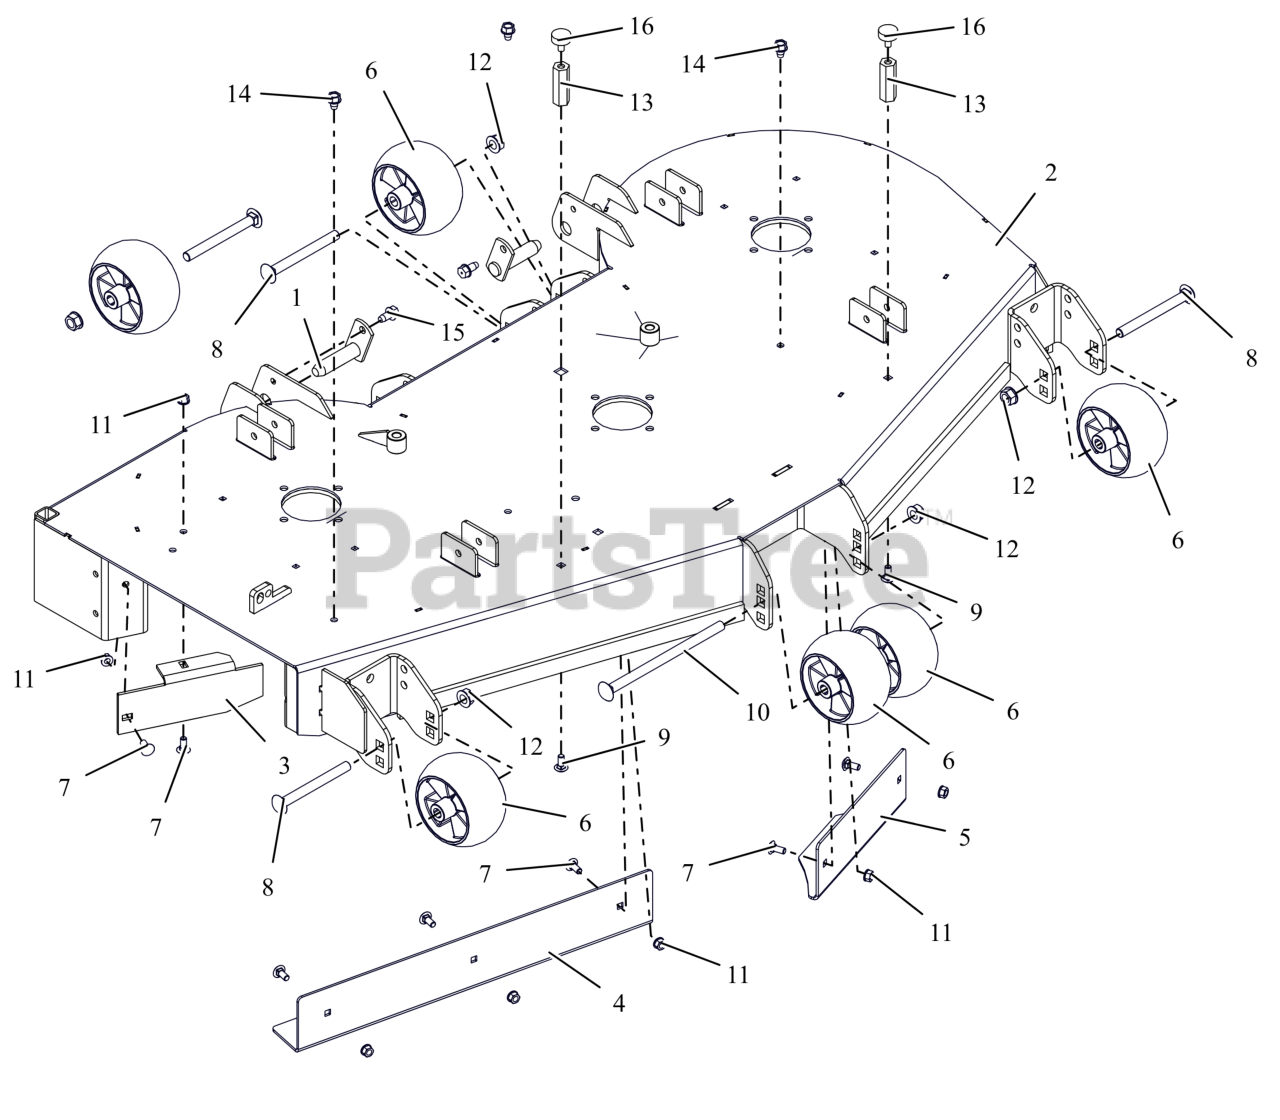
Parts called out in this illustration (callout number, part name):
1	WLDMT, MOWER MTG. PIN (BLACK)
2	KIT, 52" PRO-WALK DECK W/ DECALS (RED)
3	52" DISCHARGE BAFFLE - RED
4	BAFFLE, 52" RH VACUUM (RED)
5	BAFFLE, 52" LH VACUUM (RED)
6	WHEEL, ANTI SCALP - 5X3 CTR W/RIBS
7	BLT,RHSN .31-18X.75 G5 ZCC
8	BLT, RHSN .50-13X5.00 G5 ZCC
9	BTL,RHSN .313-18 X 0.75 G5 ZCC LT
10	BTL,RHSN .500-13 X 8.5S G5 ZCC
11	NUT,LK-CTR-FLG .31-18 GF ZCC
12	NUT-LK-CTR-FLG .500-13 GG ZCC
13	NUT, .31-18X2.25 LG COUPLING
14	SCR,TAP .375-16X.50 HWH TR ZCC
15	SCR,TAP .375-16X.75 HWH TR ZCC
16	BUMPER, RUBBER
